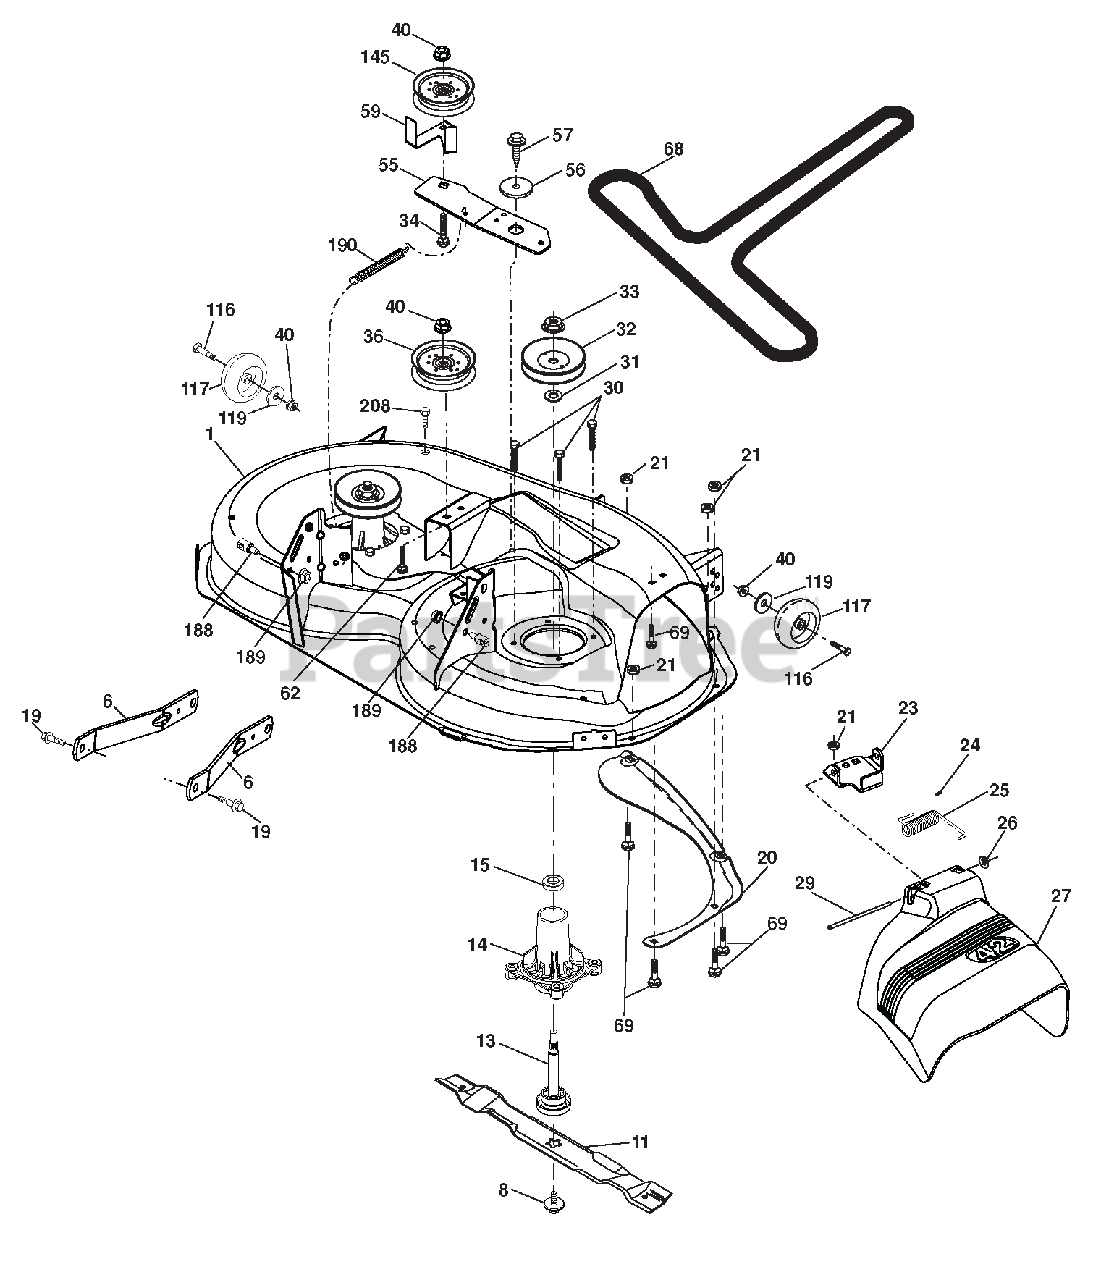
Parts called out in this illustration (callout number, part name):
1	MOWER HOUSING
1	DECK.SVC.42"HP.E.4GWB.TEX.668
6	ARM.SUSPENSION.MOWER.REAR.LD
8	BOLT/WASHER ASM.7/16-20.UNF
11	BLADE.MOWER.42"HI LIFT PREMIUM
13	SHAFT ASM.MNDRL.N/GREASEABLE38
14	HOUSING.MANDREL.4PT.SERVICE
15	BEARING.BALL.MANDREL
19	BOLT.SHOULDER
20	BAFFLE.VORTEX.42.STD/HEAVY DTY
21	Nut, Hex, Crownlock 5/16-18
23	BRACKET.DEFLECTOR.38/42"2005
24	CAP.SLEEVE..80X.112.BLK.MOWER
25	SPRING.TORSION.DFL.38/42/46.GR
26	NUT.PUSH.PHOS.& OIL
27	SHIELD.DEFLECTOR.
29	ROD.HINGE.42/46"
30	SCREW.THD ROLL.DOD PT.HEX
31	WASHER.SPACER.MANDREL
32	MANDREL.PULLEYS.42,44,50
32	MANDREL ASM.SUB.N-GRS.4 BOLT
32	- PULLEY/NUT/WASH-ER AND BLADE BOLT/WASHERS NOT INCLUDED)
33	NUT.FLANGE.LOCK.TOP
34	BOLT.CARR.SH.3/8-16X1-1/2.GR5
36	PULLEY.IDLER.4.50.RAW
40	Nut, Hex, Flangelock 3/8-16
55	IDLER.ARM
56	SPACER.RETAINER
57	SCREW.3/8-16X1.SMGML.TAP/R.BLK
59	GUARD.TUV.IDLER
62	BOLT.RD.HD.SQ.NK.3/8-16UNC X 2
68	V-Belt, 42" Mower
69	BOLT.RDHD.SQNK.5/16-18 X 5/8
116	BOLD SHLD "A" 2.41 "B" 1.66
117	WHEEL.GAGE.HALF.SPOKED
119	Washer 3/8 x 7/8 x 14 Ga.
145	PULLEY.IDLER 48"PRIMARY
188	STUD.FASTNER.W/'D'ANTI-ROTATIO
189	Nut, Lock Hex Flange 5/16-18 u
208	SCREW.THDROL.3/8-16X1/2.TYT.BL
